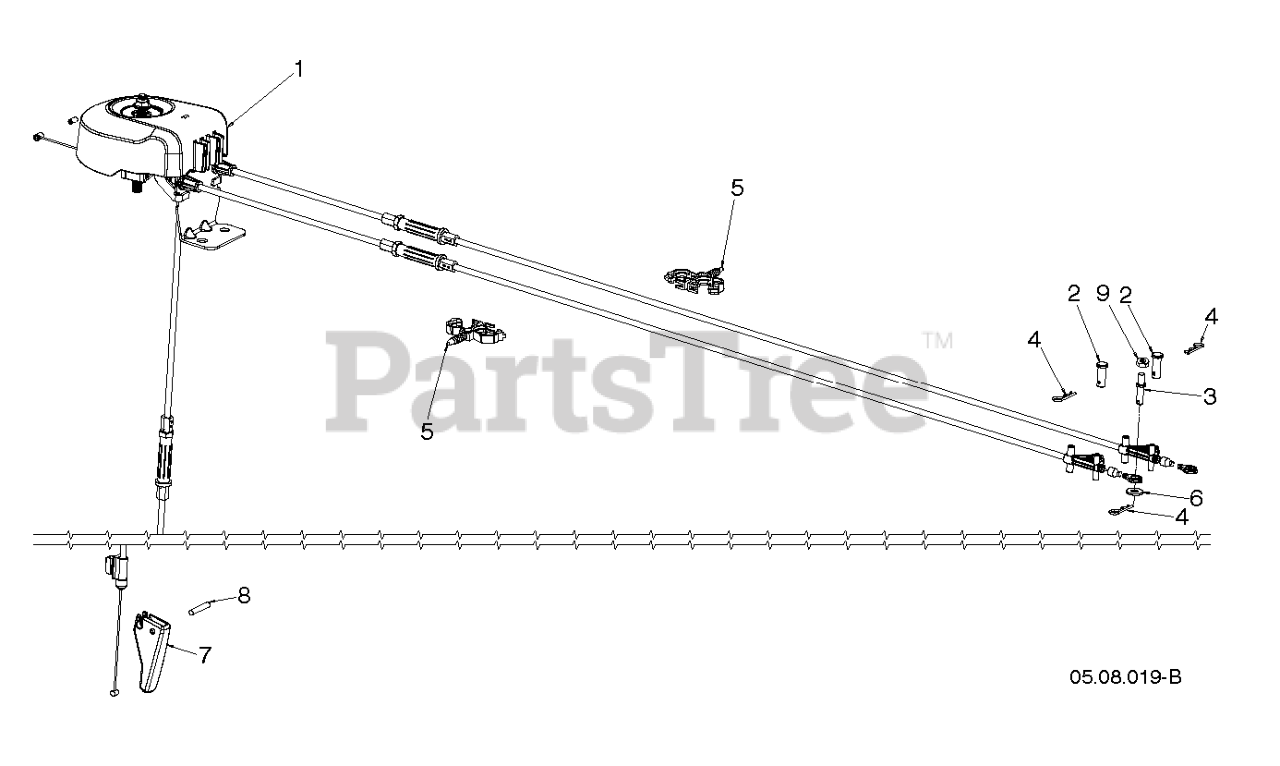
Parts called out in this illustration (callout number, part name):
1	CABLE ASSY CHUTE ROTATOR CLUTC
2	PIN CLEVIS 5/16X.875
3	Clevis Pins
4	HAIRPIN.SOFT.ZINC.059X1.125
5	CLIP.CONDUIT.DOUBLE LOOP
6	WASHER FLAT_.250 X .625 X .06
8	PIN, ROLL 3/16 X 1-1/8
9	NUT HEXAGON 1/4-20 ST ZPB
